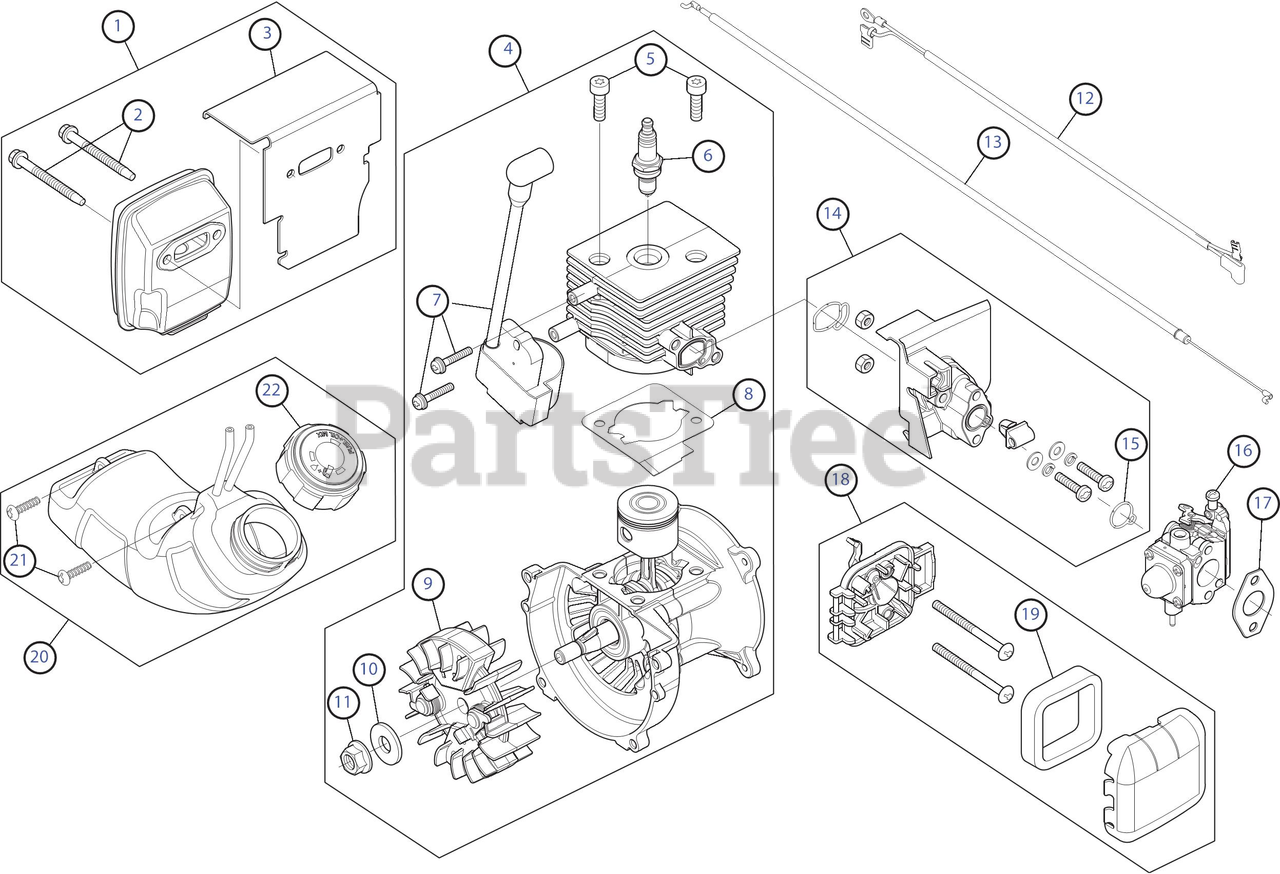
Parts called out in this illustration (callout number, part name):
1	Muffler Assembly
2	Muffler Screws
3	Muffler Gasket
4	Shortblock Assembly
6	Spark Plug
7	Module Assembly
8	Cylinder Gasket
9	Flywheel Assembly
10	Washer
12	Lead Wire
13	Throttle Cable
14	Insulator Assembly
15	Insulator O-Ring
16	Carburetor Assembly
17	Carburetor Gasket
18	Air Cleaner Assembly
19	Air Filter
20	Fuel Tank Assembly
22	Fuel Cap
